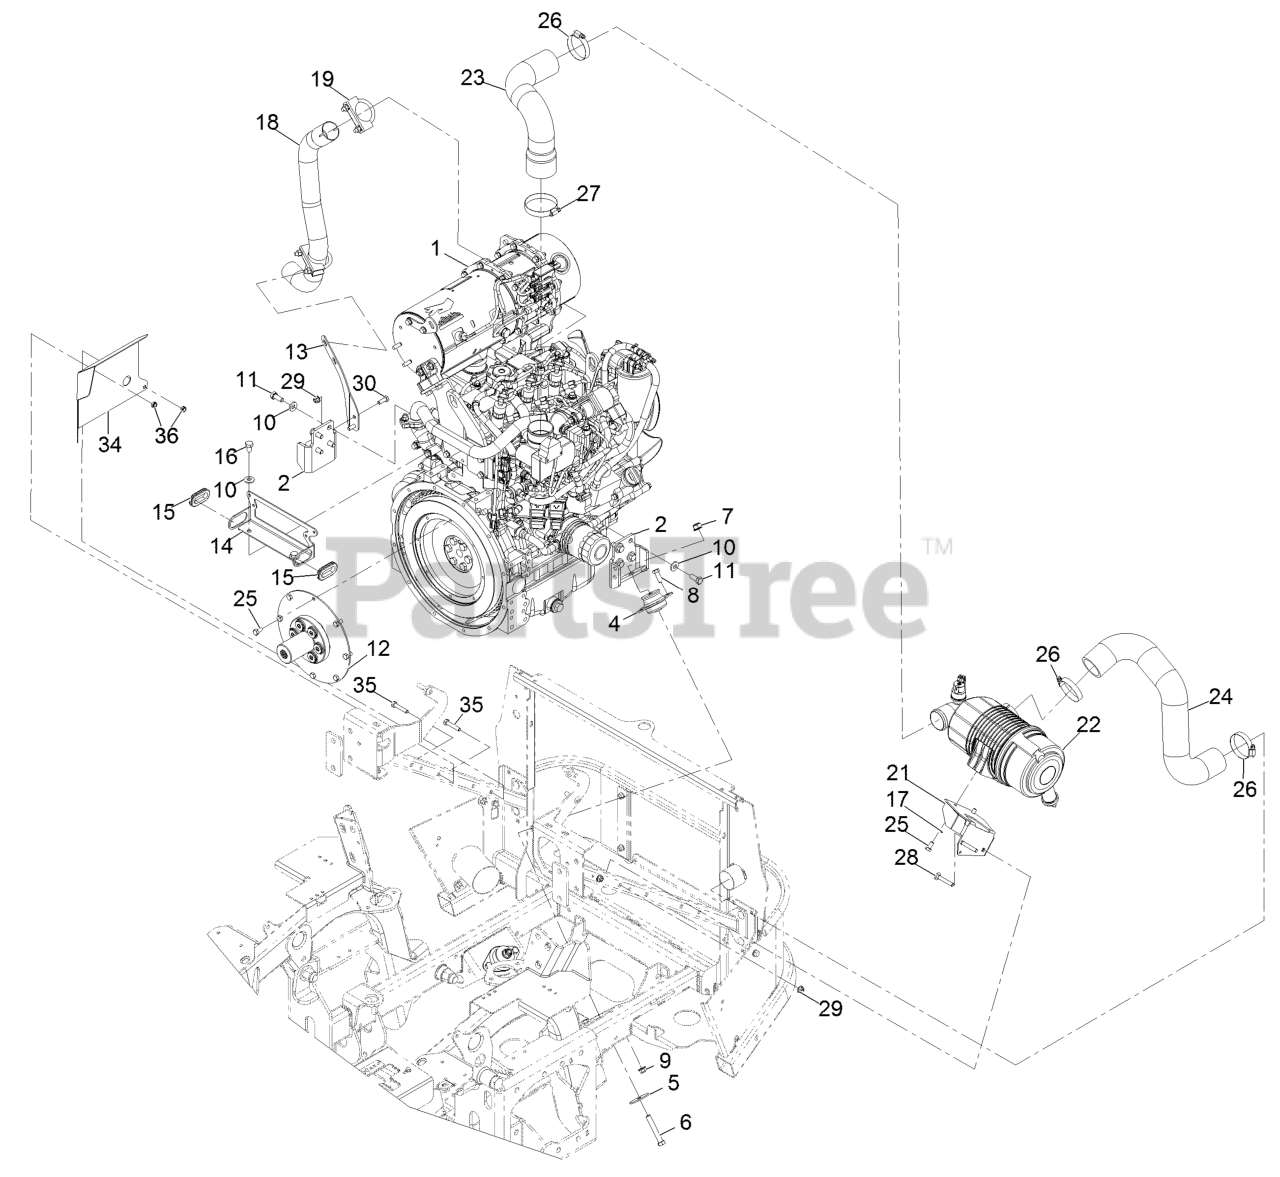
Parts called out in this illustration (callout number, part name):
1	Engine-Yanmar, 3Tnv88C-Dtr5
2	Mount-Motor, Upper
5	Washer-Snubbing
6	Screw-HH
7	Nut-HF, NI
8	Screw-HH 3/8-16 X 1
9	Nut-Nyloc 3/8-16 Flg
10	Washer-Spring Disc 3/8
11	Screw-HH M10-1.5 X 35Mm
12	Coupling-Flywheel
13	Bracket-Mount
14	Bracket-Guide
15	Grommet-Rubber
16	Screw-HH
17	Washer-Belleville
18	Tube-Exhaust
21	Bracket-Cleaner, Air
22	Air Cleaner ASM
23	Hose-Air
24	Hose-Air
25	Bolt
26	Clamp-Hose
27	Clamp-Hose
28	Bolt-Carriage 3/16-18 X 2
29	Nut-Nyloc 5/16-18 Flg
30	Screw-HH 5/16-18 X 7/8
34	Deflector-Air
35	Screw-HH
36	Nut-Nyloc 5/16-18 Thin
